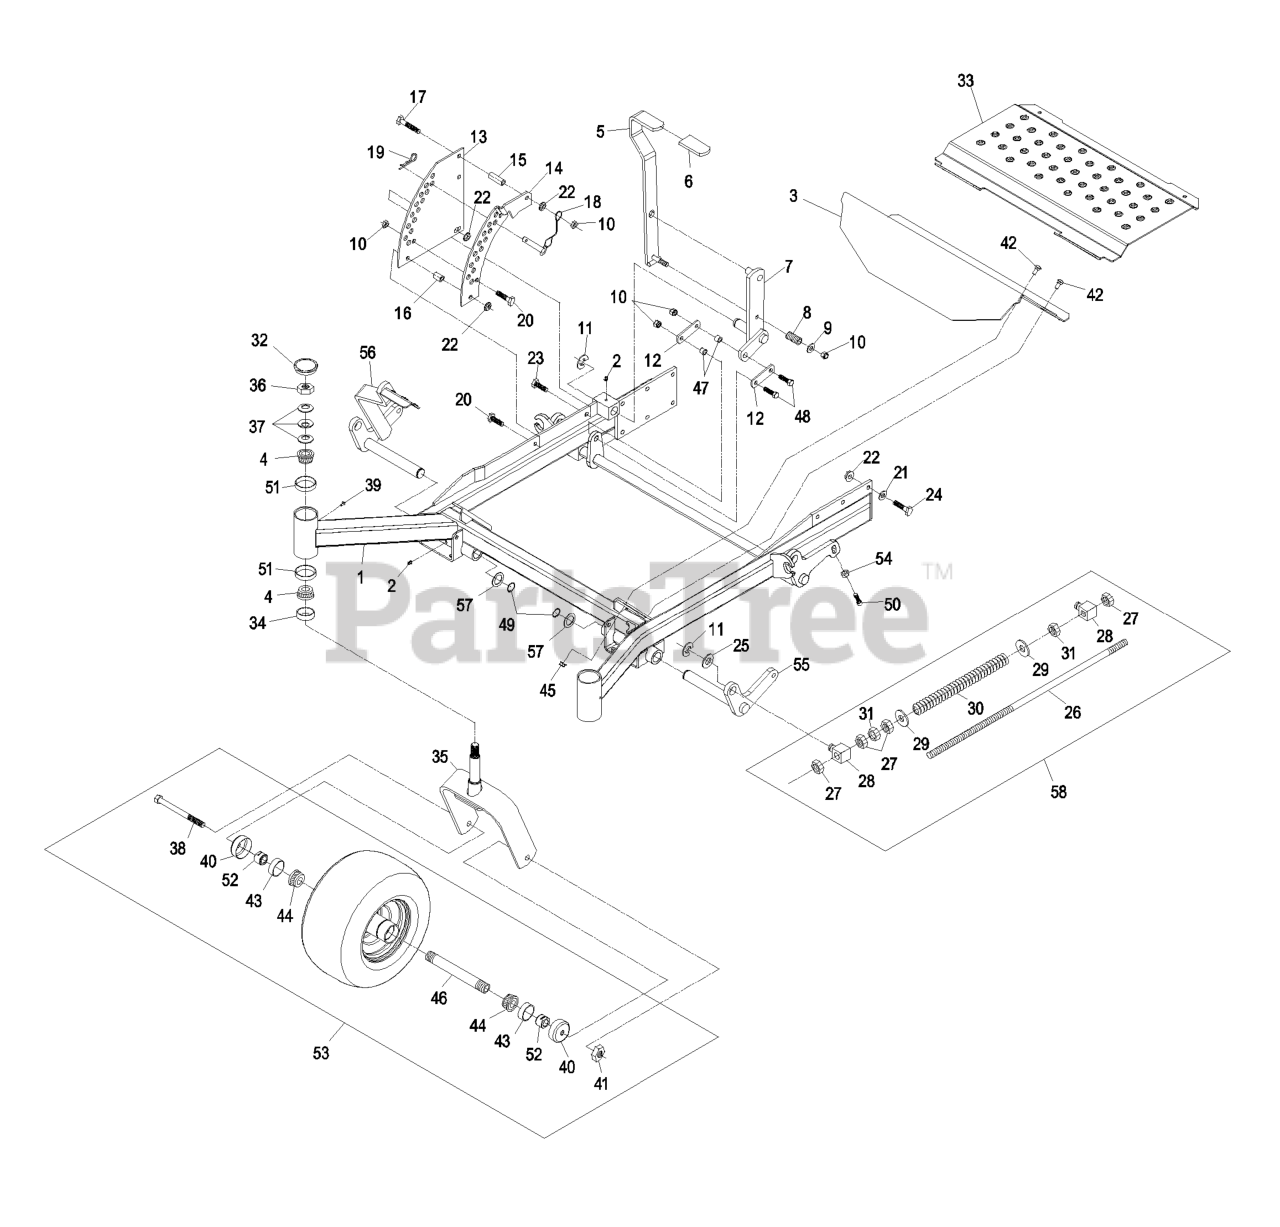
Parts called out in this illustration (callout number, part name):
1	KIT,FRONT FRAME LZ 60
2	FITTING-GREASE
3	ASM, FLOORPAN FRONT W/DEC
4	Cone-Bearing Tapered Roller
5	LIFT LEVER/GRIP ASM
6	GRIP-LEVER, LIFT
7	ARM-LIFT, DECK
8	SPRING-COMPRESSION
9	WASHER-FLAT
10	NUT-LOCK, NI
11	RING-RETAINING, EXT
12	ARM-LIFT, DECK
13	PLATE-LIFT, DECK
14	PLATE-LIFT,DECK W/DECAL L
15	BUSHING-LEVER, LIFT
16	BUSHING-LEVER, LIFT
17	SCREW-HH
18	PIN-HITCH (W/LANYARD)
19	PIN-COTTER
20	SCREW-HH
21	WASHER-BELLEVILLE
22	NUT-HHF, WHIZ
23	SCREW-HH
24	SCREW-HH
25	WASHER-FLAT
26	ROD-LIFT, DECK
27	NUT-HEX
28	SWIVEL-DECK MOUNT, REAR
29	WASHER-FLAT
30	SPRING-SUPPORT, DECK
31	NUT-JAM
32	CAP-GREASE
33	ASM, FLOORPAN LIFTOUT W/D
34	SEAL-GREASE
36	NUT-LOCK, NI
37	WASHER-BELLVILLE
38	SCREW-HH
40	GUARD-SEAL
41	NUT-LOCK, NI
42	BOLT-CARR
43	SEAL-CASTER
44	BEARING-CONE, TAPERED ROLLER
47	BUSHING
48	SCREW-HH
49	RING-RETAINING
50	SCREW-HSH
51	CUP-BEARING
52	SPACER-NUT
54	NUT-JAM
55	WLD, FRONT LIFT SHAFT - L
56	WLD, FRONT LIFT W/ LEVER
57	WASHER-SPACER
58	FRONT FRAME SPRING ASM
